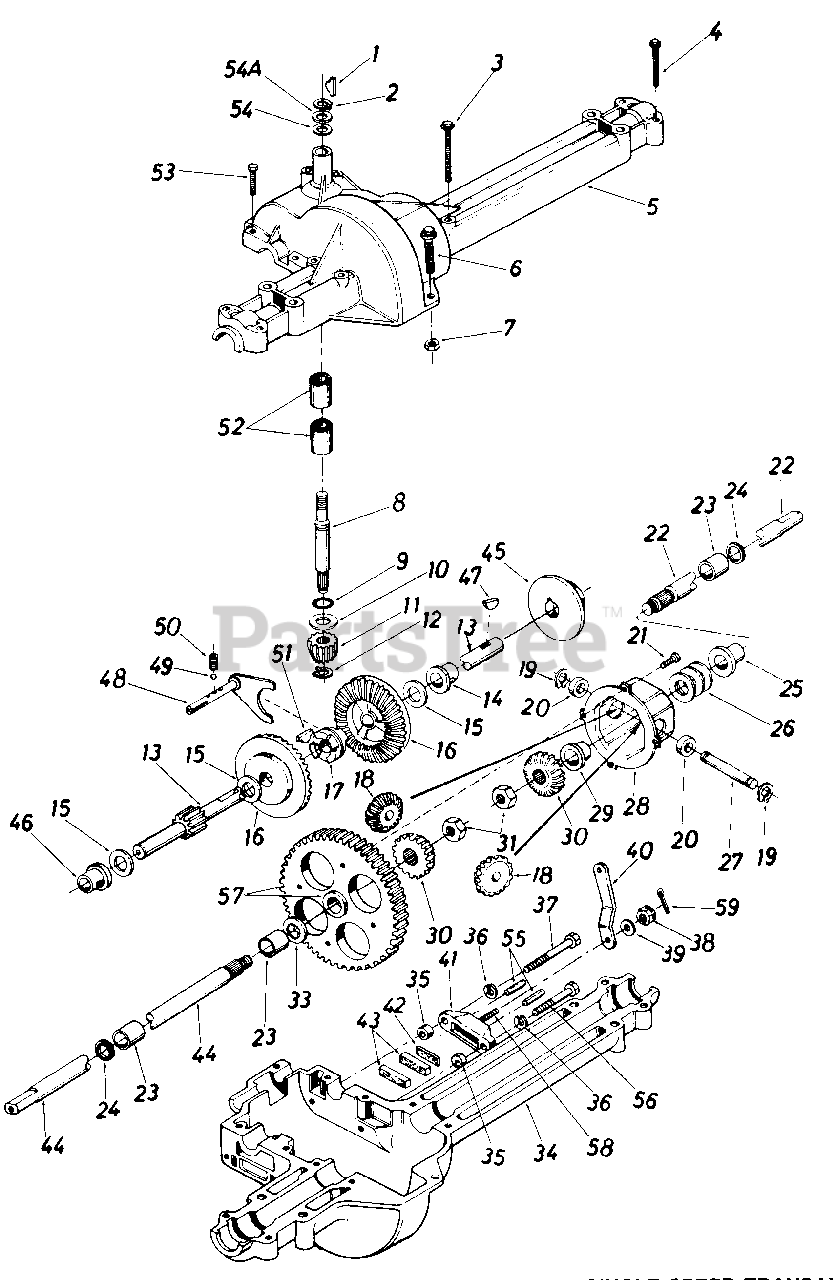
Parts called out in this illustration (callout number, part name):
1	#4 Hi-Pro Key 3/32 x 518" Dia
2	Snap Ring .625" Shaft
3	Hex Bolt 1/4-20 x 1.75" Lg.
4	Hex Bolt 1/4-20 x 1.25" Lg.
5	Upper Housing
6	Hex Fl-Bolt 1/4-20 x .75" Lg.
7	Hex Nut 1/4-20 Thd.
8	Input Shaft
9	Square Seal 5/8" I.D.
10	Thrust Washer 5/8" I.D. x 1.25" O.D.
11	Pinion Input 14T
12	Retaining Ring 7/16" Ext.
13	Drive Shaft-R.H.
14	Flange Brg. 518" I.D. x 3/4"
15	Fl-Wash.
16	Bevel Gear 42T
17	Clutch Collar
18	Miter Gear 15T
19	Snap Ring
20	Thrust Bearing 1/2" I.D. x 1.0" O.D.
21	Pan Head Scr. 1/4-20 x .50" Lg. w/Patch
22	Axle R.H.
23	Sleeve Bearing 3/4" I.D. x 1.0" Lg.
24	Oil Seal 3/4" I.D.
25	Flange Bearing 3/4" I.D. x 15/16" Lg.
26	Fl-Wash. .760" I.D. x 1.49" O.D.
27	Cross Shaft
28	Differential Housing Ass'y.
30	Miter Gear
31	Hex Ins. L-Nut 1/2-20 Thd.
33	Fl-Wash. .75" I.D. x 1.5" O.D.
34	Lower Housing
35	Spacer .53" O.D. x 3/8" Lg.
36	L-Wash. 1/4" I.D.
37	Hex Bolt 1/4-20 x 1.50" Lg. (Grade 5)
38	Castle Nut 5/16-24 Thd.
39	Fl-Wash. .34" I.D. x .875" O.D.
40	Actuating Arm-R.H.
41	Brake Yoke
42	Puck Plate
43	Brake Puck
44	Axle L.H.
45	Brake Disc
46	Flange Bearing 5/8" I.D. x 15/16" Lg.
47	Woodruff Key 3/16 x 5/8 HT
48	Shift Fork Ass'y.
49	Ball Detent .250" Dia.
50	Spring Detent
51	#9 Hi-Pro Key 3/16" x 3/4" Dia. HT
52	Needle Brg. 5/8" I.D. x 1/2" Lg.
53	Hex Bolt 1/4-20 x 1.00" Lg.
54	Fl-Wash. 5/8" I.D. x .030
54A	Fl-Wash . 5/8" 1. D . x .040
55	Actuating Pin 5/16" Dia.
56	Hex Bolt 1/4-20 x 1.50" Lg. (Grade 5)
57	Differential Gear 72T Ass'y. w/ Bearing
58	Sq. Hd. Bolt 5/16-24 Thd.
59	Cotter Pin 3/32" Dia. x .50"
